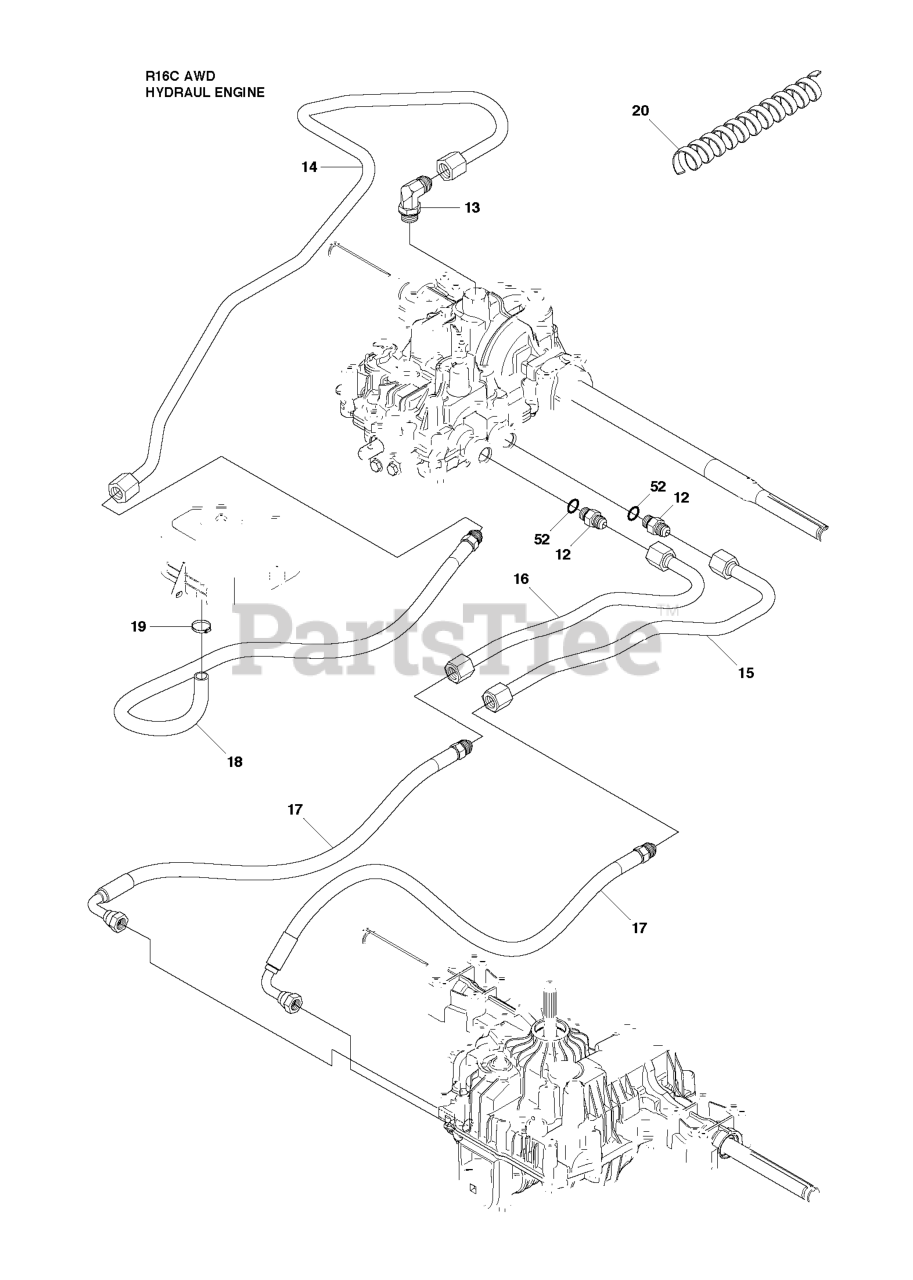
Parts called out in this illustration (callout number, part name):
12	PIPE FITTING
15	HYDRAULIC PIPE
16	HYDRAULIC PIPE
17	HYDRAULIC HOSE
20	HOSE GUARD D=43 L=400
